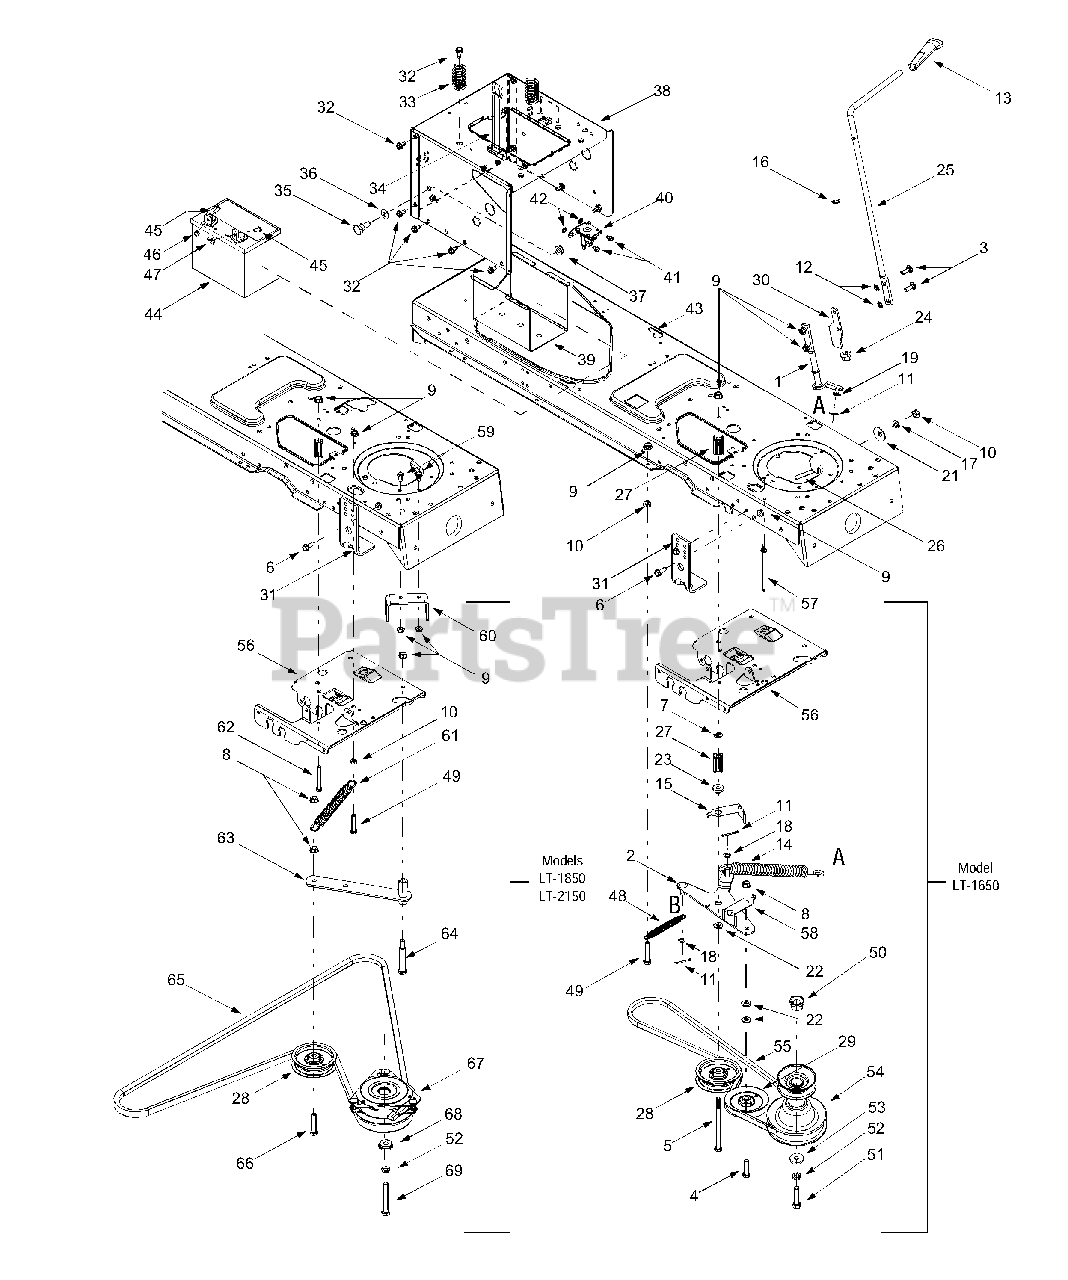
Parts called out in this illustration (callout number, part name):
1	PTO Engage Lever Assembly
4	Hex Cap Screw, 3/8-16 x 1.5
5	Hex Cap Screw, 3/8-16 x 5.5
6	Hex Head Washer Screw, 5/16-18 x .875
7	Push Nut, 3/8
8	Flange Lock Nut, 3/8-16
9	Flange Lock Nut, 5/16-18
10	Hex Nut, 5/16-18
11	Cotter Pin, 1/8 x 1.25
12	Speed Nut, .3125
13	PTO Knob
14	Extension Spring, .75 x 6.75
16	Flat Washer, .510 x .750 x .033
17	Lock Washer, 5/16
18	Flat Washer, .385 x .62 x .063
19	Flat Washer, 5/16
21	Bell Washer, .39 x 1.13 x .062
22	Flat Washer, .407 x .812 x .135
23	Shoulder Spacer, .380
24	Hex Split Flange Bearing, .5
26	Belt Keeper Rod
27	Spacer, 3/8 x 1.54
28	Idler Pulley, 3.5
29	Idler Pulley, 4.0
32	Self Tapping Screw, 5/16-18 x .625
33	Compression Spring, 1.28 x 3.5
34	Battery Strap
35	Shoulder Screw, .625 x .5, 7/16-20
36	Bell Washer, .45 x 1.0 x .062
37	Flange Lock Nut, 7/16-20
41	Self Tapping Screw, 1/4-20 x .5
42	Lock Washer, 1/4
45	Hex Cap Screw, 1/4-20 x .62
46	Hex Sems Nut, 1/4-20
47	Wing Nut, 1/4-20
48	Extension Spring, .50 x 5.0
49	Hex Cap Screw, 5/16-18 x 1.75
50	Spacer Cup
51	Hex Head Cap Screw, 7/16-20 x 1.25
52	Lock Washer, 7/16
53	Flat Washer, .450 x 1.25
54	Engine Pulley, 3.56 OD x 5.56
55	PTO Belt (Two Belt design)
55	PTO/Deck Belt (One Belt)
57	Keeper Pin, 5/16 x 4.75
58	Belt Guard
59	Hex Cap Screw, 5/16-18 x .625
62	Hex Cap Screw, 3/8-16 x 2.5
65	PTO Belt
66	Hex Cap Screw, 3/8-16 x 2.0
67	Electric PTO Clutch
68	Shoulder Spacer, 1.38 x .445 x .36
69	Hex Cap Screw, 7/16-20 x 3.25 (Grade 5)
